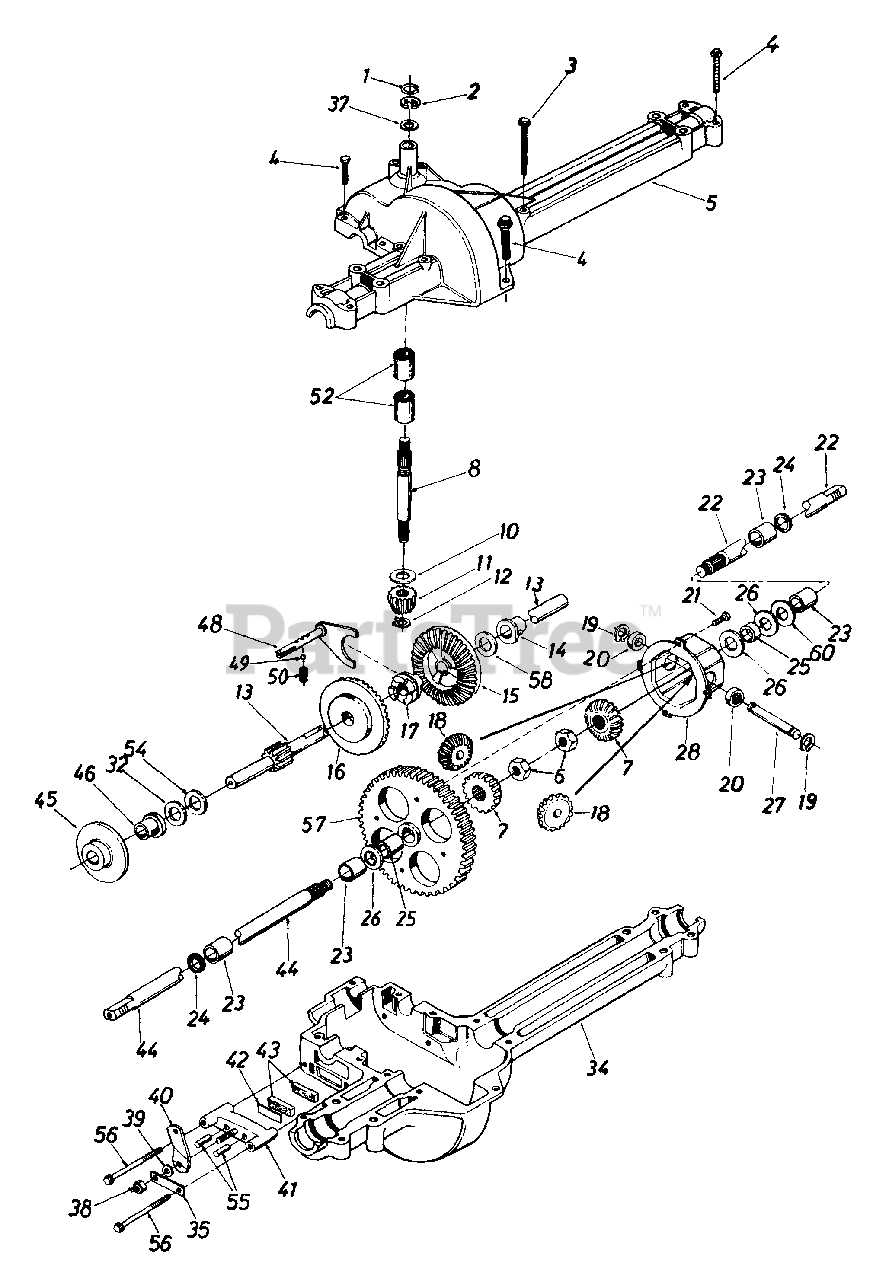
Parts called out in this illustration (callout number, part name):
1	Wire Ring
2	E - Ring
3	Hex Bolt 1/4-20 x 1.75" Lg.
4	Hex Tap Scr. 1/4-20 x 1.25" Lg.
5	Upper Housing
6	Hex Jam Nut 1/2-20 Thd.
7	Miter Gear
8	Input Shaft
10	Thrust Washer 5/8" I.D. x 1.25" O.D.
11	Pinion Input 14T
12	Retaining Ring
13	Drive Shaft - L.H. Brake
14	Flange Brg. 5/8" I.D. x 3/4" Lg.
15	Bevel Gear 42T - Small I.D.
16	Bevel Gear 42T - Large I.D.
17	Clutch Collar
18	Miter Gear 15T (H.D.)
19	Snap Ring
20	Thrust Bearing
21	Pan Head Scr. 1/4-20 x .50" Lg. w/Patch
22	Axle R.H.
23	Sleeve Bearing 3/4" I.D. x 1.0" Lg.
24	Oil Seal 3/4" I.D.
25	Axle Spacer
26	Fl-Wash..760" I.D. x 1.5" O.D.
27	Cross Shaft
28	Differential Can Ass'y.
32	Thrust Wash. 5/8" I.D. x 1" O.D. x .025" Thk.
32	Fl-Wash. 5/8" I.D. x 1" O.D. x .030" Thk.
32	Thrust Wash. 5/8" I.D. x 1" O.D. x .035" Thk.
32	Fl-Wash. 5/8" I.D. x 1" O.D. x .040" Thk.
34	Lower Housing
35	Anti-Rotation Brkt.
37	Fl-Wash. 5/8" I.D. x 1" O.D. x .020" Thk.
37	Fl-Wash. 5/8" I.D. x 1" O.D. x .030" Thk.
37	Fl-Wash. 5/8" I.D. x 1" O.D. x .040" Thk.
38	Hex Nut 5/16-24 Thd.
39	Fl-Wash..344" I.D. x .875" O.D.
40	Actuating Arm
41	Brake Yoke
42	Puck Plate
43	Brake Puck
44	Axle L.H.
45	Brake Disc
46	Flange Bearing 5/8" I.D. x 15/16" Lg.
48	Shift Fork Ass'y.
49	Ball Detent .250" Dia.
50	Spring Detent
52	Needle Brg. 5/8" I.D. x 1/2" Lg.
54	Fl-Wash. 5/8" I.D. x 1" O.D. x .020 Thk.
55	Actuating Pin 5/16" Dia.
56	Hex Wash Hd. Self-Tap Scr. 1/4-20 Thd.
57	Differential Gear 58T
58	Fl-Wash. 5/8" I.D. x 1" O.D. x .020 Thk.
58	Thrust Wash. 5/8" I.D. x 1" O.D. x .025" Thk.
60	Fl-Wash..76" I.D. x 1.5" O.D. x .010" Thk.
60	Fl-Wash..76" I.D. x 1.5" O.D. x .020" Thk.
60	Fl-Wash..76" I.D. x 1.5" O.D. x .030" Thk.
60	Fl-Wash..76" I.D. x 1.5" O.D. x .060" Thk.
